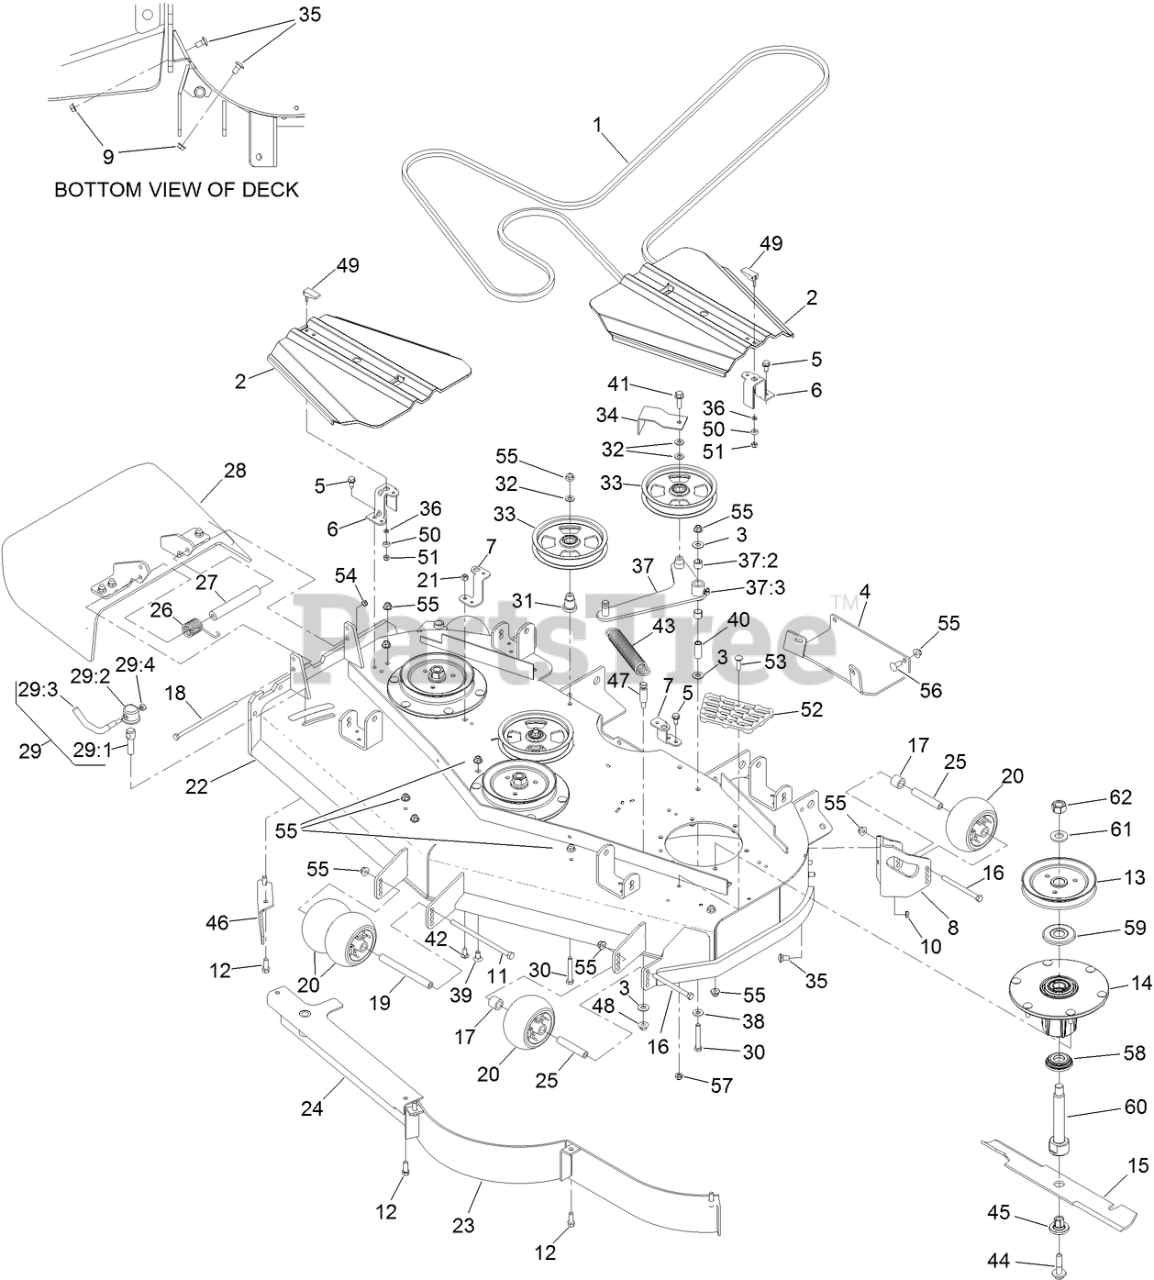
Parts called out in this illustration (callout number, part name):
1	BELT-V
2	COVER-BELT
3	WASHER-FLAT
4	PLATE-SKID
5	SCREW-HWHTF
6	BRACKET-COVER
7	BRACKET-COVER, TALL
8	MOUNT-WHEEL, LH
9	NUT-HHF, WHIZ
11	SCREW-HH
13	SHEAVE-BLADE, DRIVE
14	SPINDLE ASM
15	BLADE-FLOW, HIGH
16	SCREW-HH
17	TUBE-SPACER
18	SCREW-HH
19	SPACER-WHEEL
20	ROLLER-SCALP, ANTI
21	NUT-LOCK, NI
22	DECK ASM
25	TUBE-SPANNER
26	SPRING-TORSION
27	SPACER
28	RUBBER DEFLECTOR ASM
29	LEVER ASM
29:1	SCREW-LOCK
29:2	CAP-LOCK
29:4	NUT-LOCK, NI
30	SCREW-HH
31	MOUNT-PULLEY
32	WASHER-FLAT
33	PULLEY-IDLER, FLAT
34	GUIDE-BELT
35	SCREW-CARR
36	WASHER
37	DECK IDLER ARM ASM
37:2	SLEEVE-BEARING
37:3	FITTING-GREASE, 90 DEG
38	WASHER-BELLEVILLE
39	SCREW-CARR
40	BUSHING
41	SCREW-HHF
42	SCREW-CARR
43	SPRING-EXTENSION
44	SCREW-SEMS
45	BUSHING-HEX
46	BAFFLE-DISCHARGE
47	PIN-THREADED, SPRING ANCHOR
48	NUT-HF
49	HANDLE-LATCH, SWELL
50	BUSHING-LATCH, SWELL
51	NUT-LOCK, HH
52	STEP-DECK
53	SCREW-CARR
54	NUT-LOCK, NI
55	NUT-HF, NI
56	SCREW-CARR
57	NUT-HF, NI
58	GUARD-BOTTOM
59	GUARD-BEARING, TOP
60	SHAFT-SPINDLE
61	WASHER
62	NUT-HEX
